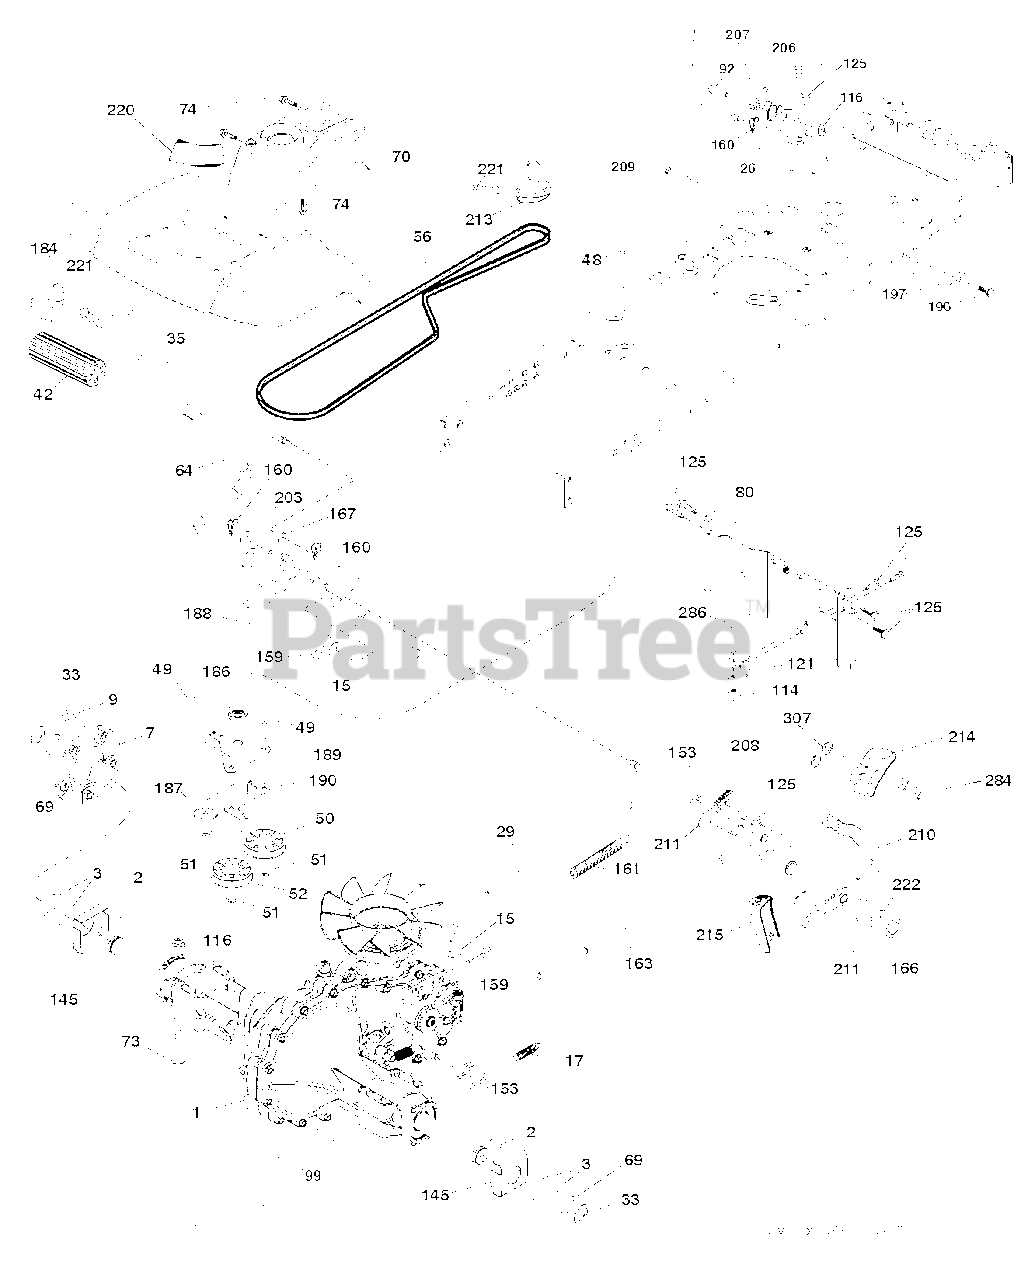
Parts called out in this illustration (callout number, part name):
2	KEY 1/4 X 2.5
7	HUB.ASM.WHEEL.REAR.23"TEX
15	WASHER
17	SPRING.BRAKE.HG3000/3500
26	SPRING.RETURN.CRUISE
33	E RING HYT
35	ROD.BRAKE.PARTK.HUSQ.TEX
42	PEDAL COVER T
48	BOLT.3/8-16X1.50
50	IDLER.FLAT.910.OFFSET
51	NUT LOCK FLG 3/8-16 UNC
52	IDLER.V-GROOVE.910.OFFSET
56	V-BELT.GROUND.DRIVE.
64	SHAFT.ASM.PEDAL.BRK.CNTR
70	CONSOLE.ASM.RH.GT.FC.HUSQ
73	BOLT HEX FLGHD 5/16-18X3 GR. 5
74	SCREW.HI-LO.CONSOLE
80	STRAP.TORQUE.YT.G700
92	BOLT
99	SPRING.BYPASS.YT.G700
114	NUT.71038.31-18.HEX.NYLOCK
116	NUT LOCK HEX FLANGE 5/16-18
121	BRACKET STRAP TORQUE
125	SCREW
145	WASHER.AXLE.FLANGE.HG-3000
153	RETAINER M
159	COTTER PIN
160	RETAINER CLIP
161	SPRING, RETURN LT
163	ROD PEDAL CONTROL
166	NUT.PUSH.625
167	LATCH.BRAKE.SPRING
184	RB HANDLE.PARKG.BRK.HUS/PRED
186	SPACER.RETAINER
187	WASHER 12/32X2X10GA
188	RP LINK.CLUTCH.GROUND.DRIVE
189	BELLCRANK.GROUND.DRIVE.TRAPPED
190	KEEPER BELLCRANK ROUND DRIVE
196	SCREW 3/8-16X1
197	BRKT.ANIT-ROTATION.CLUTCH
203	WASHER
206	BRKT.MOUNT.LATCH.CRUIS
207	LATCH.CONTROL.CRUISE
208	GEAR.SECTOR.CONTROL.CR
209	ROD.CONTROL.CRUISE.GT.
210	ROCKER.ASM.PEDAL.CONTR
211	BEARING.NYLON
213	KNOB.CONTROL.CRUSIE.HU
214	PEDAL.FORWARD.HUSQVARNA.DEALER
215	PEDAL.REVERSE.TEX.GT.4
220	REFLECTOR.RH.TEX GT
221	RETAINER.SPRING.CLIP.H
222	WASHER 21/32 X 1-1/4 X 10 GA.
284	NUT.U-CHNL.1/4-20.550DP.350PNL
286	BOLT.5/16-18X2.5
307	SCREW.MACHINE.CR.1/4-20
